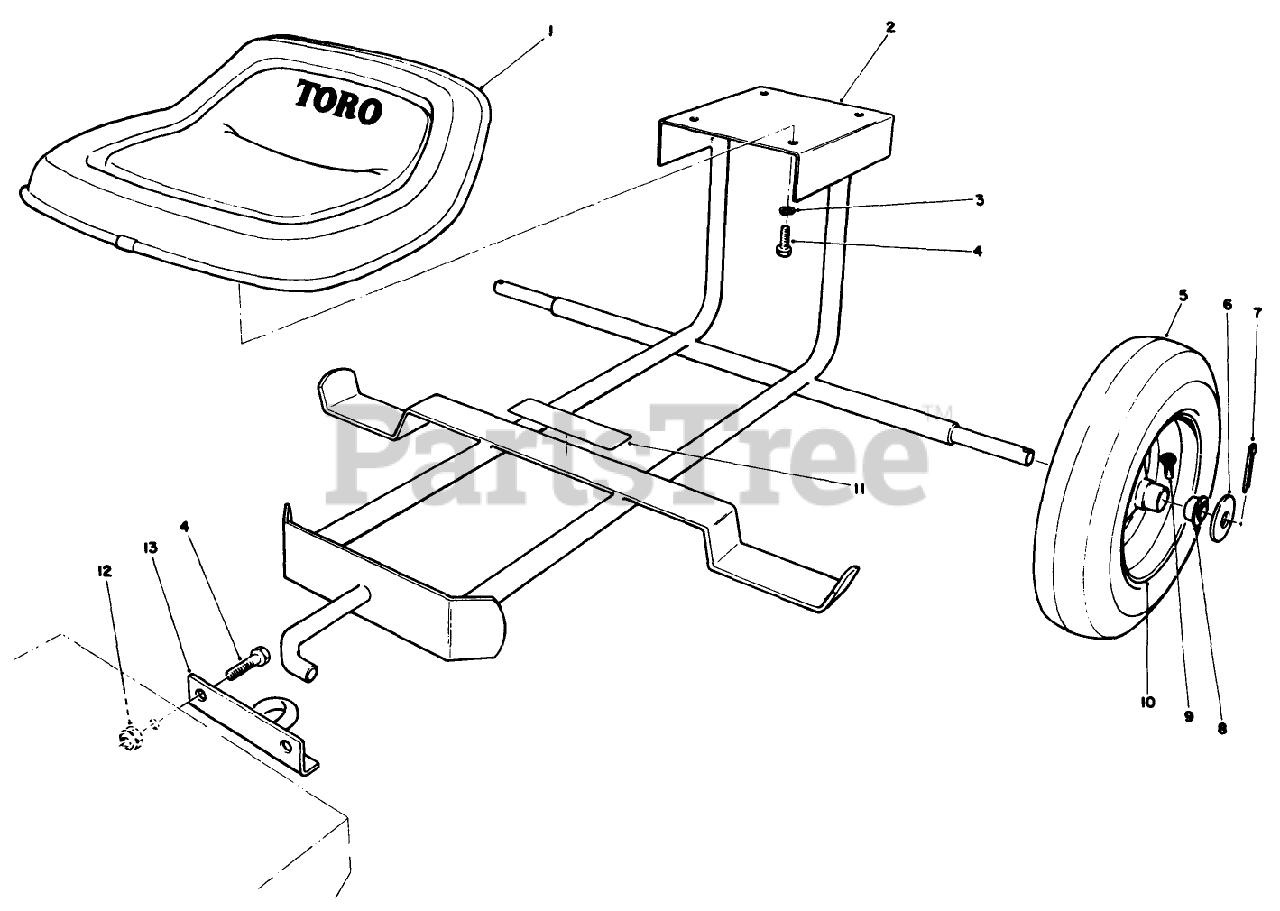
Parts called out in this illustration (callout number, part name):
3	WASHER-LOCK
4	SCREW-HH
6	WASHER-FLAT
7	PIN-COTTER
9	INNER TUBE VALVE STEM
12	NUT-LOCK, NI
13	HITCH WA *R
